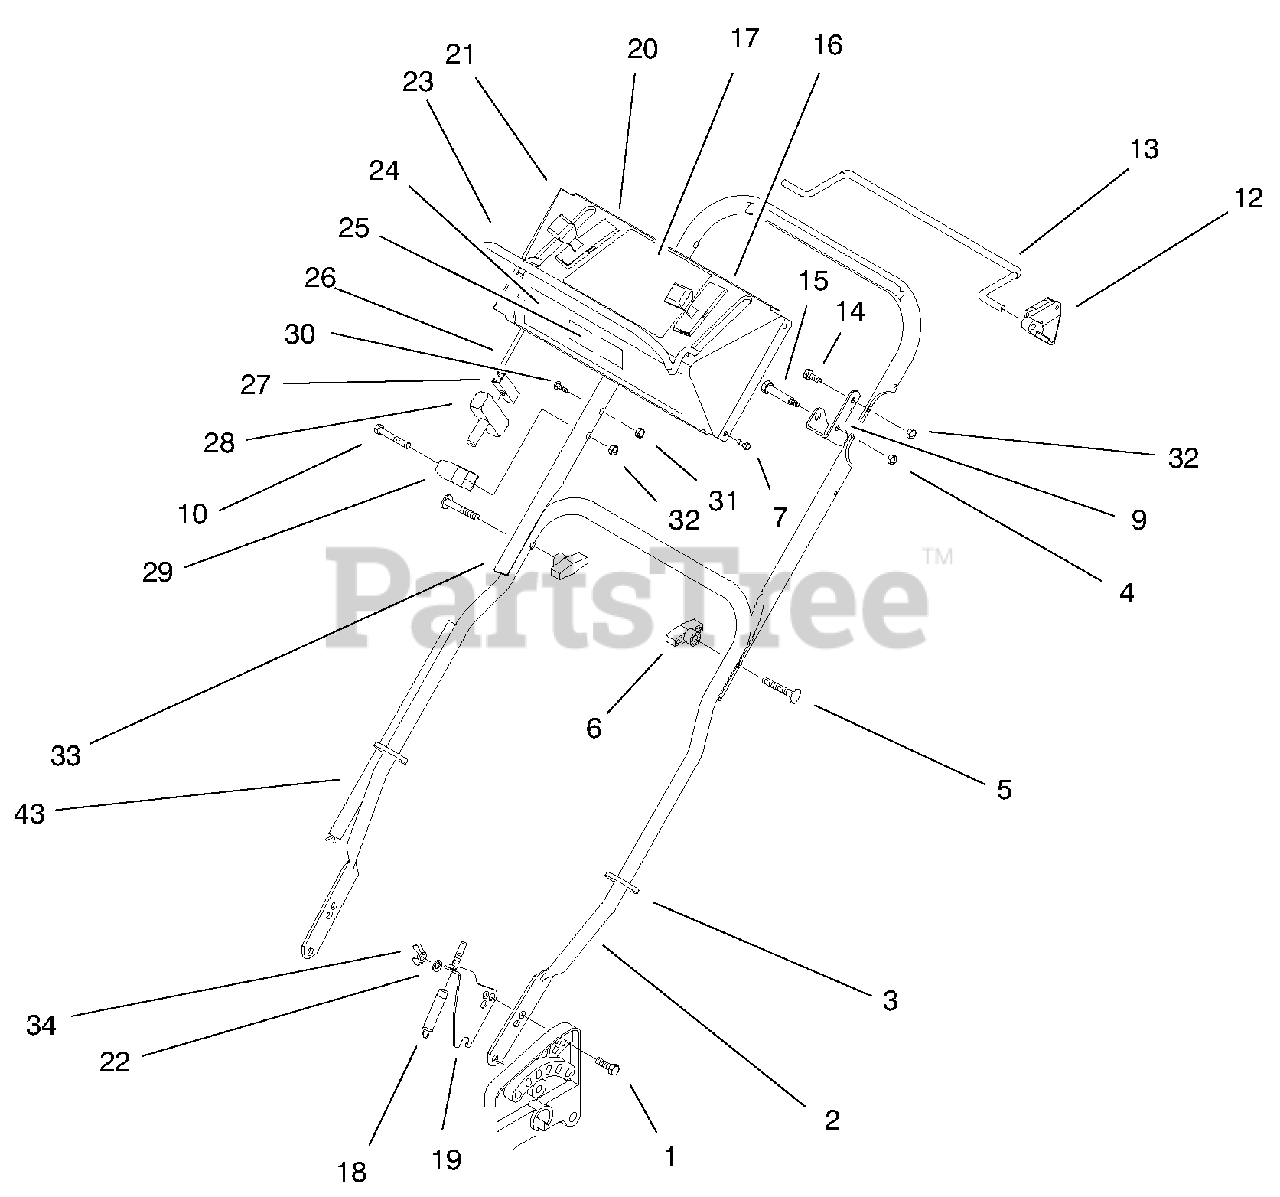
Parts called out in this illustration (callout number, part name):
1	Bolt-CARR
2	Handle Section-Lower
3	Tie Strap
4	Nut-Lock
5	Screw-Handle
7	Screw-Phil
9	Bail Stop Bracket
10	Bolt-Hex
12	Stop-Pivot
13	Bail-Sp Control
14	Screw-HH
16	Throttle Cable
17	Decal-Control Panel
19	Bracket-Traction Cable
20	Control-Speed
21	Panel-Control
22	Washer-Lock
23	Engine Control Bail
24	Decal-Panel Sp
26	Cable-Control
27	Clip-Rope
28	Handle-Starter
29	Guide-Rope
30	Handle Screw
31	Bracket-Cable Anchor
32	Nut-Lock
33	Handle-Upper
